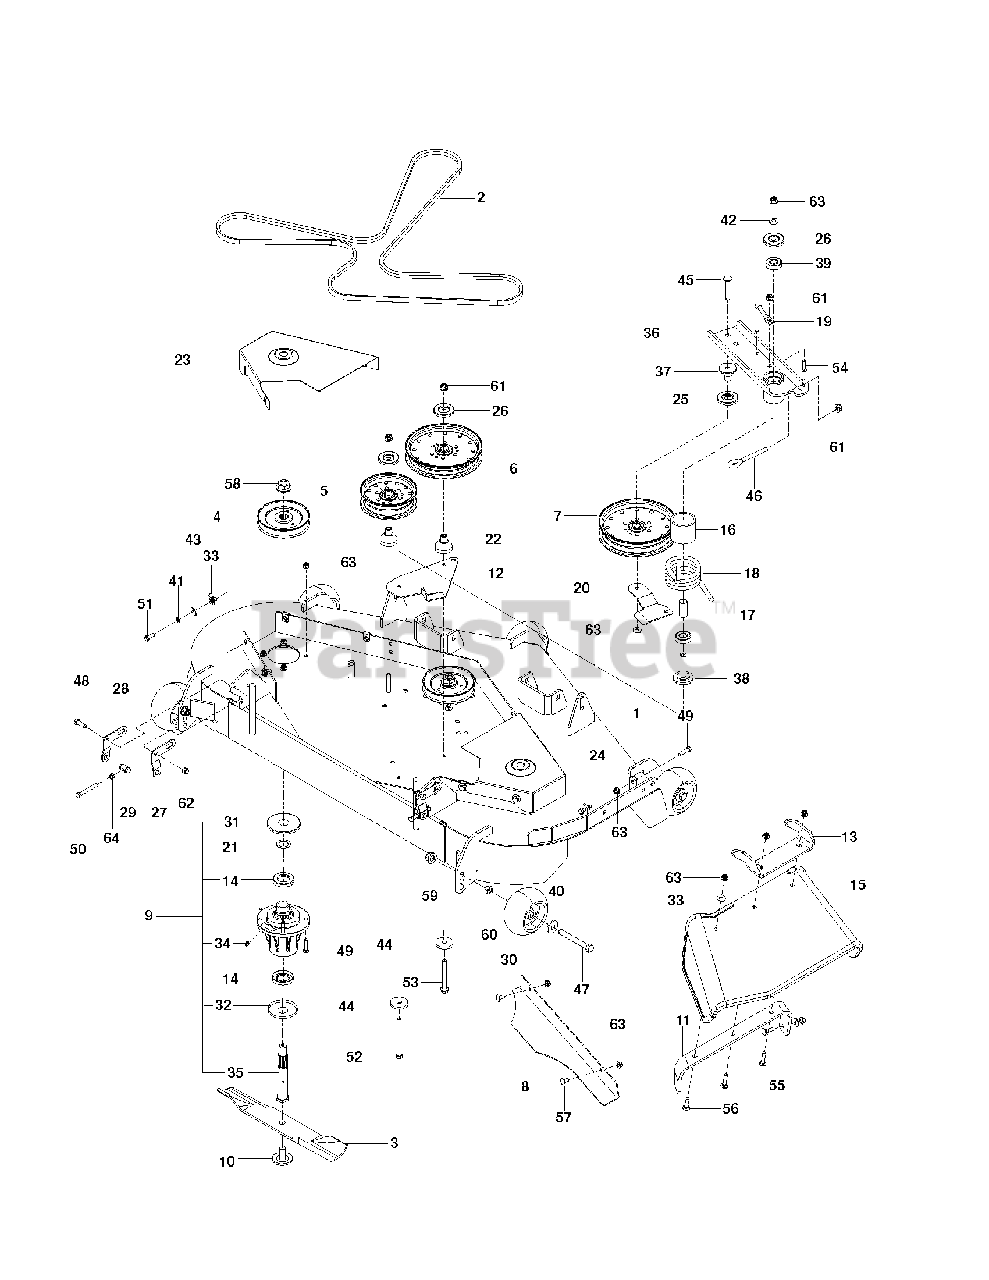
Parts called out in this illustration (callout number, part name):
1	DECK W/DECALS DX152
2	BELT DECK DX152
4	PULLEY 52
5	IDLER PULLEY
6	PULLEY - 7" NARROW
7	PULLEY - IDLER 7"
8	CONFINEMENT PLATE, 52"
10	BLADE BOLT/WASHER
11	BRKT, REINF - CHUTE 52/61"
12	BRACKET, SPRING STOP
13	PIVOT BRACKET - CHUTE
14	SHAFT SEAL
15	CHUTE, RUBBER DISCHARGE 52/61"
17	SPACER, IDLER BEARINGS
20	BELT GUIDE, BLK
21	MACHINE BUSHING
22	BEARING, IDLER STANDOFF
23	SHIELD, BELT, 52 RT, BLUE
24	SHIELD, BELT, 52 LT, BLUE
25	SHIELD, DUST
26	DUST SHIELD
29	TRUNION, PITCH
31	TOP DUST CAP
32	BOTTOM DUST CAP
33	U-CLIP 5/16-18 NUT RETAINER
34	PLUG-VENTED
36	IDLER.ARM.BLACK
37	BEARING, IDLER ARM
38	BEARING, IDLER PIVOT
39	BEARING, BALL
40	WASH USS FLAT 1/2
41	WASH 5/16 DISC SPRING ZD
42	WASHER, 3/8 THICK
43	WASHER 5/16 FLAT
44	SPINDLE WASHER
45	CARRIAGE BOLT 3/8-16 X
47	HCS 1/2-13 X 4 GR 5 ZD
48	HCS 3/8C X 1
49	HCS 5/16C X 1 1/4
50	HCS 5/16-18 X 2 1/2 TPBLT
51	HCS 5/16C X 3/4
52	HCS 3/8-16 X 4-1/2 GR 8 ZD
53	HHFS 3/8-16 X 3 GRD 5 ZD
54	RHSSNB 5/16C X 1.0
55	RHSNB 5/16-18 X 1-1/2 GR 5 ZD
56	BOLT, CARRIAGE 5/16X1-1/4
57	CARRIAGE BOLT 5/16C X 5/8"
58	NUT FLANGE 3/4-16
59	NUT, 1/2-13 HEX FLG NYLOC ZD
60	NUT 1/2 HEX JAM
61	NUT 3/8-16 HEX FLG NYLOC ZD
62	NUT 3/8-16 NYLOC
63	5/16-18 NYLOC FLANGE NUT
64	NUT 5/16C HEX
